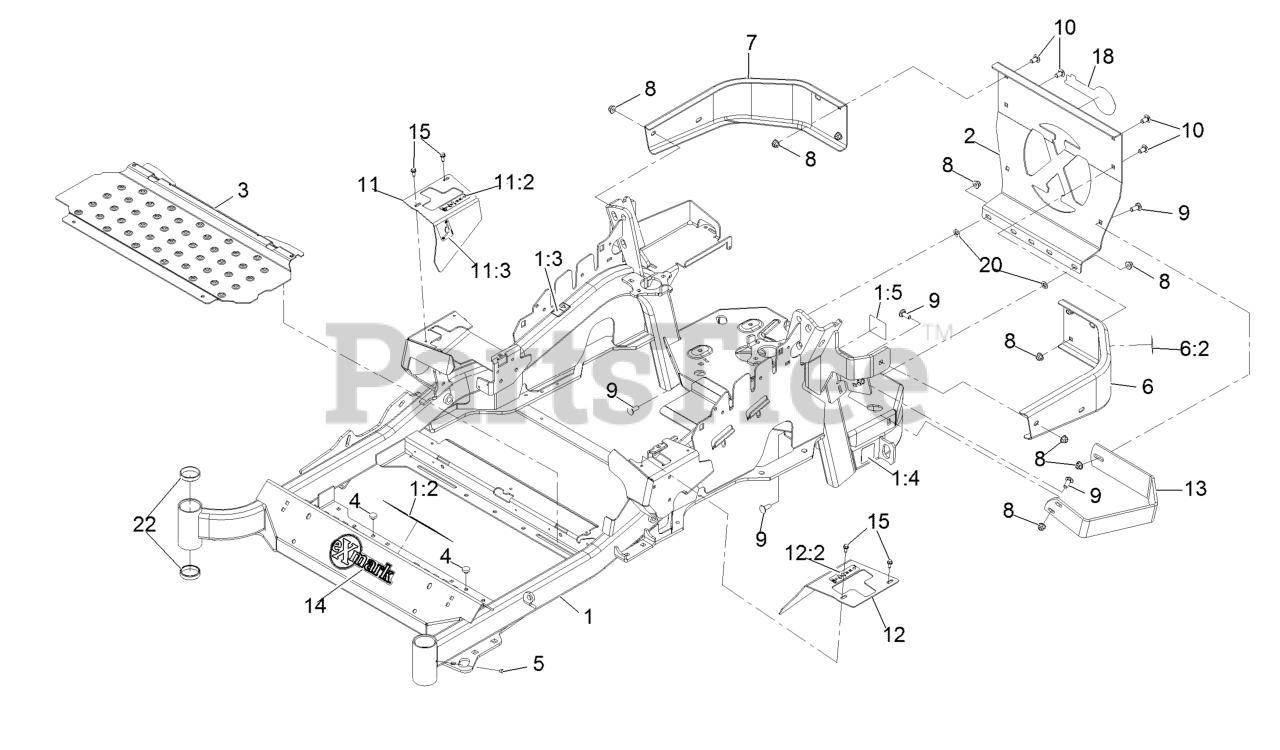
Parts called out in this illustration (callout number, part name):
1	Mainframe ASM
1:2	Decal-Danger
1:3	Decal-Warning
1:4	Decal-Hazard, Pinched Finger
1:5	Decal-Spark Arrester
2	Plate,Rear Guard
6	LH Bumper ASM
6:2	Decal-Warning
7	Bumper-RH
8	Nut-Nyloc 3/8-16 Flg
9	Bolt-Carriage 3/8-16 X 1
10	Bolt-Carriage 3/8-16 X 3/4
11	RH Motion Control Cover ASM
11:2	Decal-Control, Motion
11:3	Decal-Park Brake, CE
12	LH Motion Control Cover ASM
12:2	Decal-Control, Motion
13	Guard-Muffler
14	Decal-Exmark
15	Screw-HWH 1/4-20 X .62
18	Decal-Exmark Logo
20	Nut-Push 3/8-16
22	Cup-Bearing Tapered Roller
